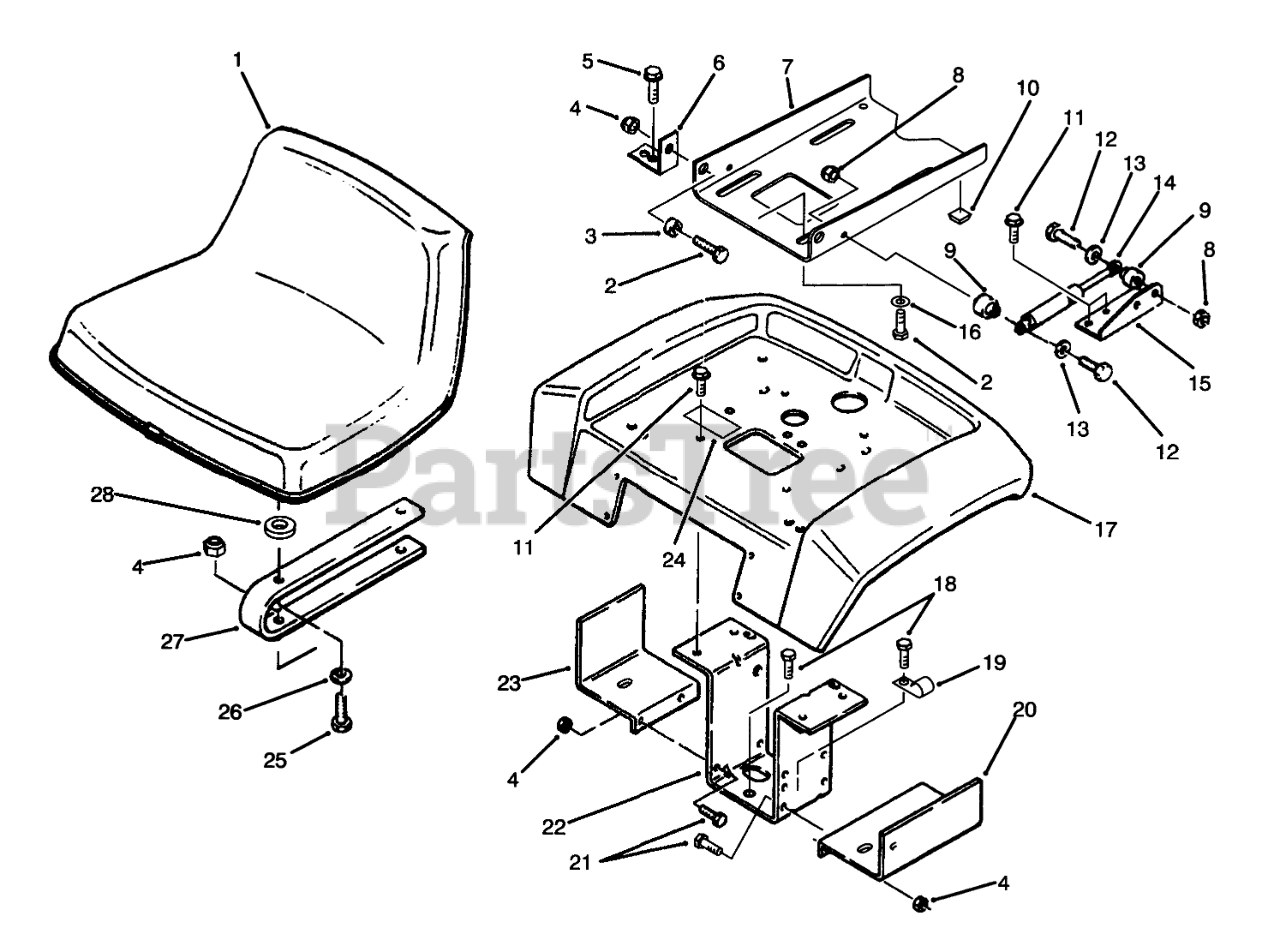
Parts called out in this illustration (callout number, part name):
1	SEAT V-510
2	SCREW-HH
3	BUSHING
4	NUT-LOCK, NI
5	Bolt
6	BRACKET-PIVOT
7	Plate-SeatPivot
8	NUT-LOCK, NI
9	SPACER
10	BUMPER SJ5514 BLACK
11	SCREW
12	SCREW-HH
13	WASHER-FLAT
14	GAS SPRING
15	BRACKET-CYLINDER R
16	WASHER-PLAIN
17	Fender
18	SCREW-HH, LOCK
19	CLIP
20	Fuel Tank Support LH
21	SCREW-HH
22	Bracket-Fender
23	Support-FueITank RH
24	DECAL-DO NOT TOW
25	SCREW-HH
26	WASHER-LOCK
27	Seat Spring
28	SPACER-NYLON
